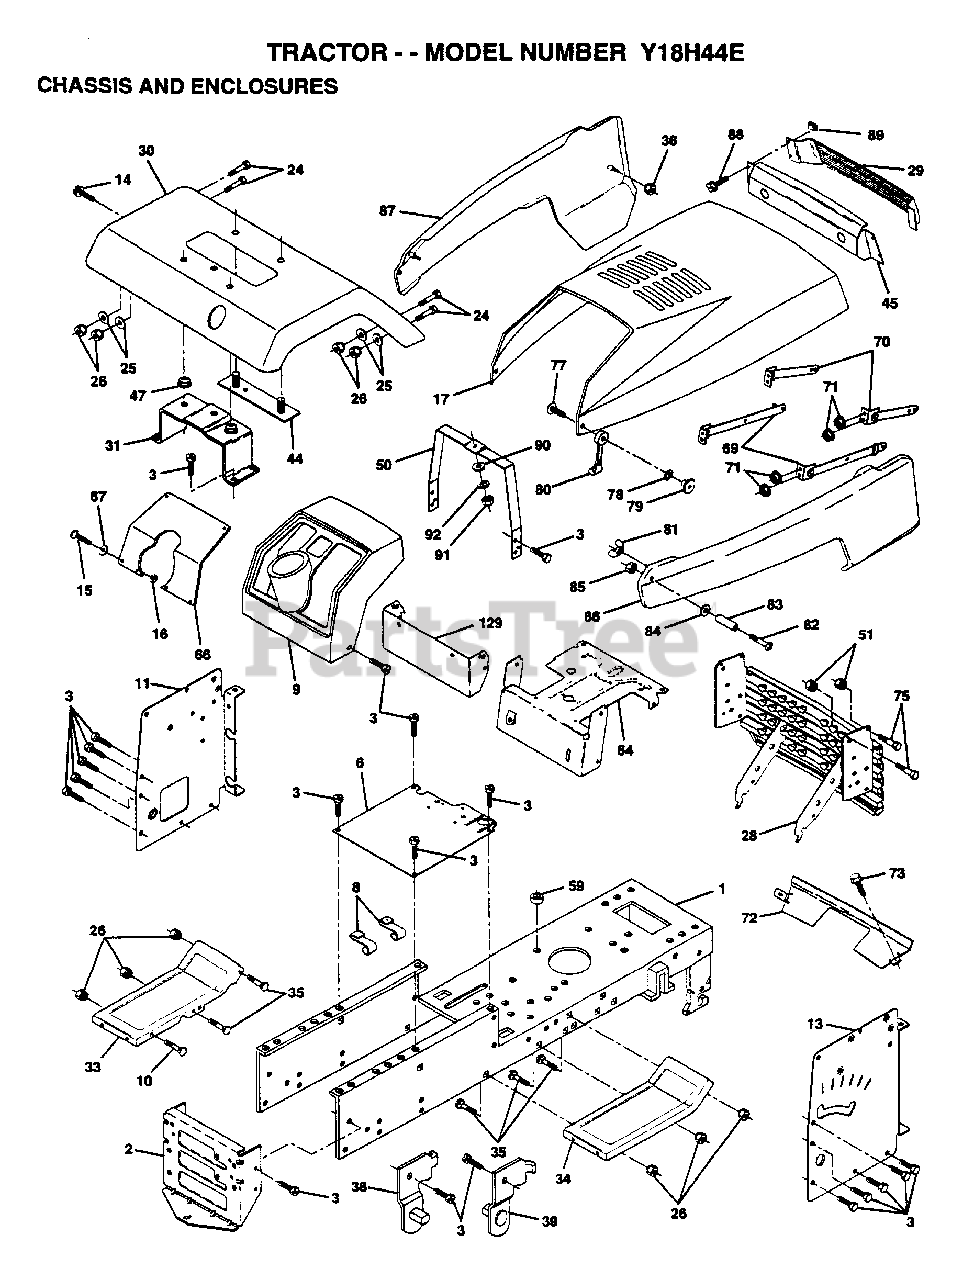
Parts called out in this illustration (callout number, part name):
1	CHASSIS.WLD.11GA
3	SCREW
8	"CLIP,INSULATOR"
9	DASHBOARD BLACK
11	PANEL.DASH.LH.
13	PANEL.DASH.RH.
14	SCREW LT
15	SCREW
17	"PANEL,SIDE RH"
24	BOLT
25	WASHER
26	NUT
29	LENS LT
30	FENDER.PNT.
31	BRKT.ASM.FENDER
35	BOLT
36	PAL NUT LT
38	BRACKET ASM LH
39	BRACKET ASM RH
44	STRAP ASM FENDER
47	NUT-PUSH YT
50	DASH.SUPT.YP/HUSQ
51	NUT
66	PLATE SLKSCR YP
71	NUT HXKEP 1/4X20
72	STRAP.GRILLE.PNT.
73	SCREW CRT
77	SCREW
78	LOCKWASHER
79	WELDNUT
80	HOOD LATCH T
82	SCREW
83	SPACER LT
84	WASHER
86	PANEL SIDE RH
89	"""J"" FASTENER LT"
90	WASHER PM
92	LOCKWASHER
129	DASH.EXT.PNT.
